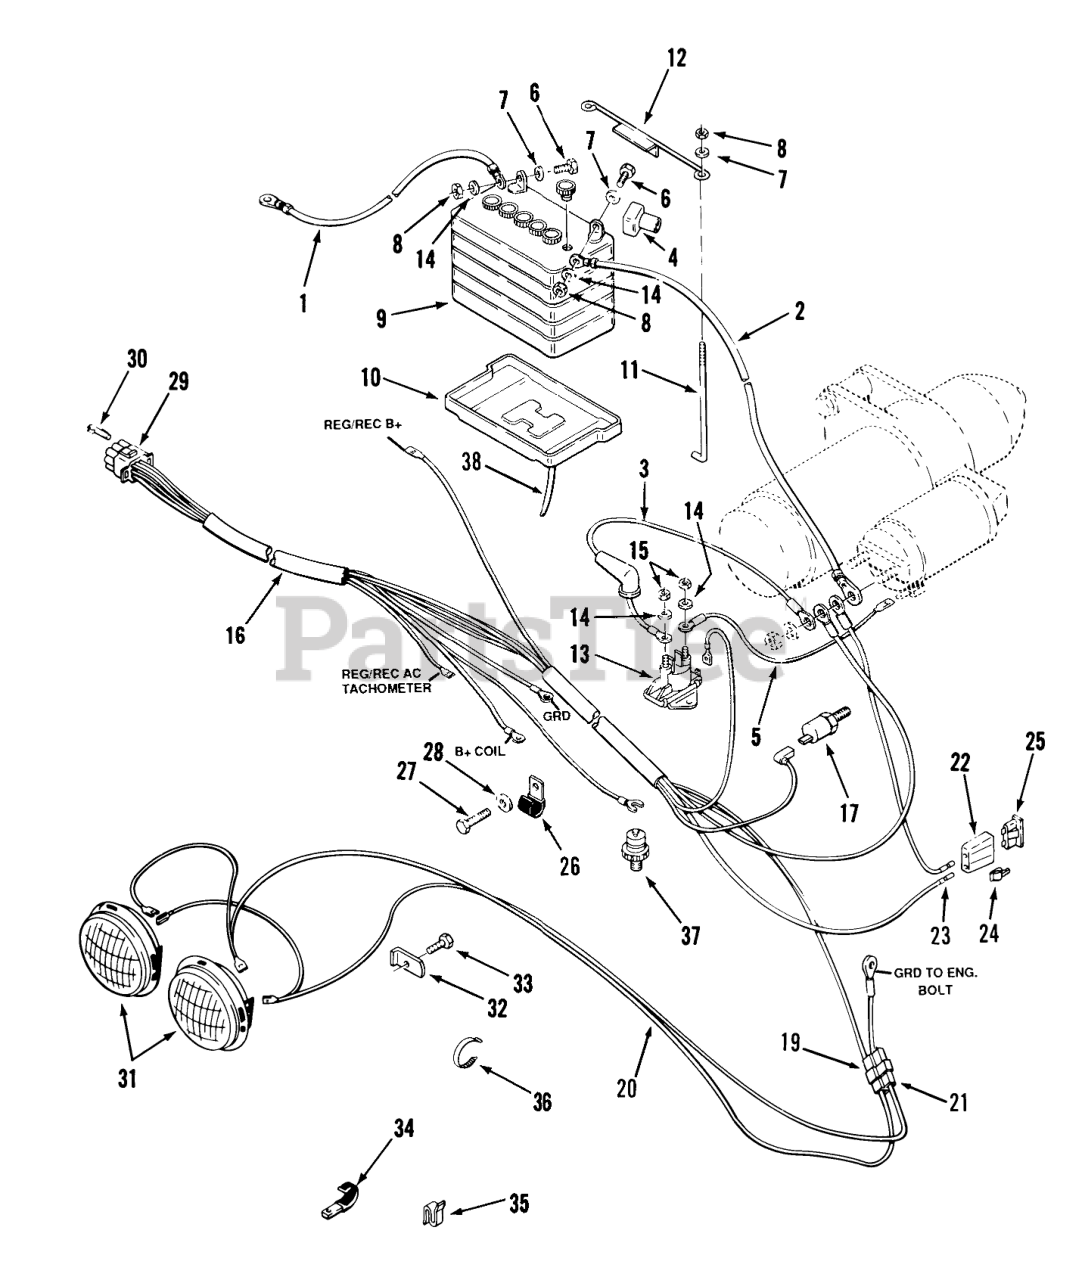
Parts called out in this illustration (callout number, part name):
1	ASS'Y-WIRE
2	ASS'Y-WIRE
3	ASS'Y-WIRE
4	Boot
5	ASS'Y-WIRE
6	Bolt
8	Nut
9	Battery
9	Battery Maintenance Free 416
10	TRAY-BATTERY
11	HOOK-BATTERY RETAIN
12	HOLDDOWN-BATTERY
13	SOLENOID-STARTER
14	Washer
15	Nut
16	Engine Wiring Harness
17	HIGH TEMPERATURE
18	RECEPTACLE TERMINAL
19	MALE CONNECTOR
20	HARNESS-HEADLIGHT
20	HARNESS-HEAD LIGHT
21	CONNECTOR BODY
22	AUTO-FUSEBLOCK TERM
23	TERMINAL FUSE
25	FUSE-30 AMP
26	Clip
27	Bolt
28	LOCKWASHER 1/4 IT
29	CONNECTOR CAP
30	CONTACT SOCKET
31	HEAD LAMP
31	HEADLAMP
32	LOCK-HEADLIGHT
33	Bolt
34	CLIP
35	SPEED CLIP
36	PLASTIC TIE
37	LOW OIL PRESSURE
38	TUBE-21" BATTERY DRAIN
53	WASHER
